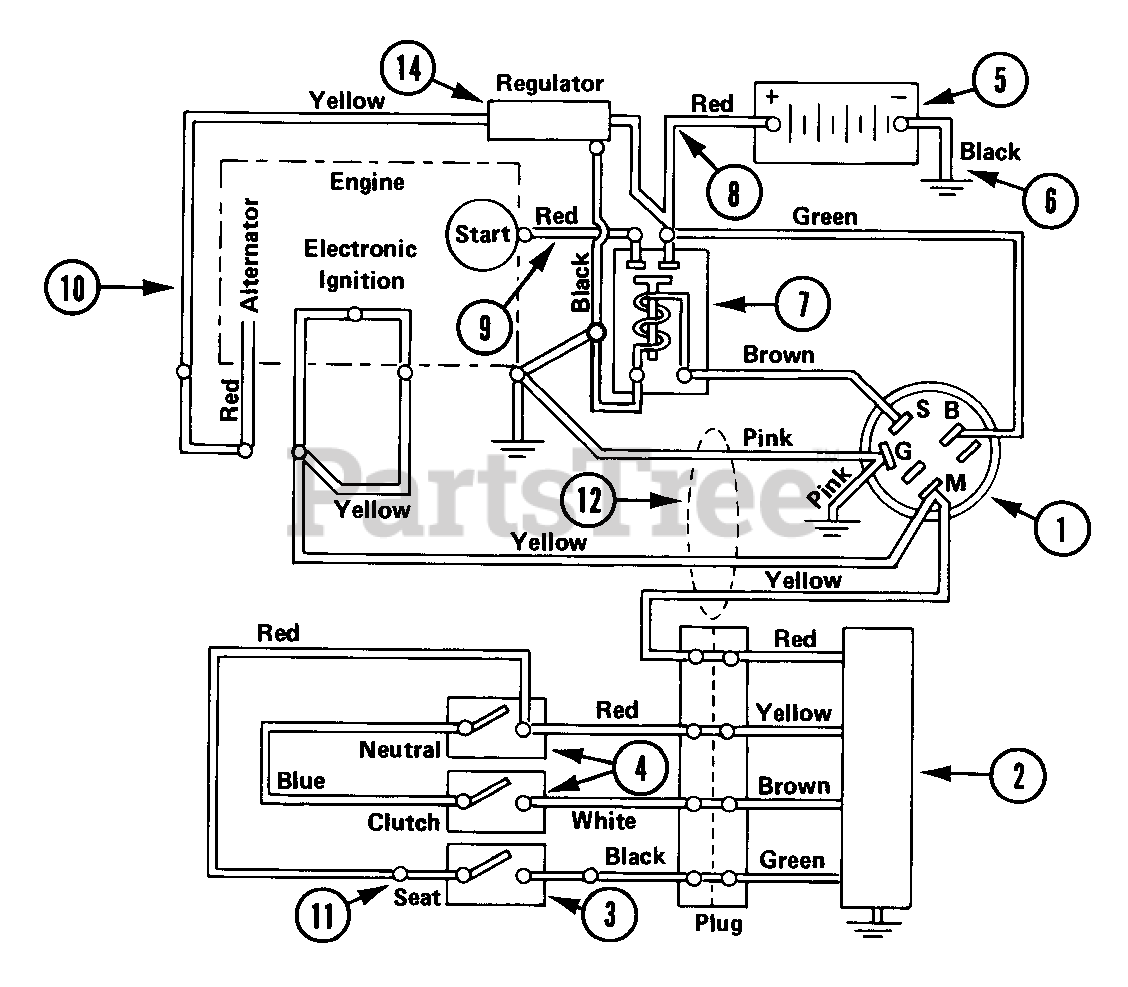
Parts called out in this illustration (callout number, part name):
1	IGNITION SWITCH ASSEMBLY
2	MODULE
3	SAFETY SWITCH
3	SEAT WITH SWITCH REPLACEMENT P
3	SWITCH SEAT
4	SWITCH INTERLOCK
5	BATTERY
6	GROUND CABLE .25X13.00X.31
7	SOLENOID
8	STARTER CABLE 16"
9	STARTER CABLE 13"
11	ADAPTER - SEAT SWITCH
12	WIRE HARNESS
14	REGULATOR
